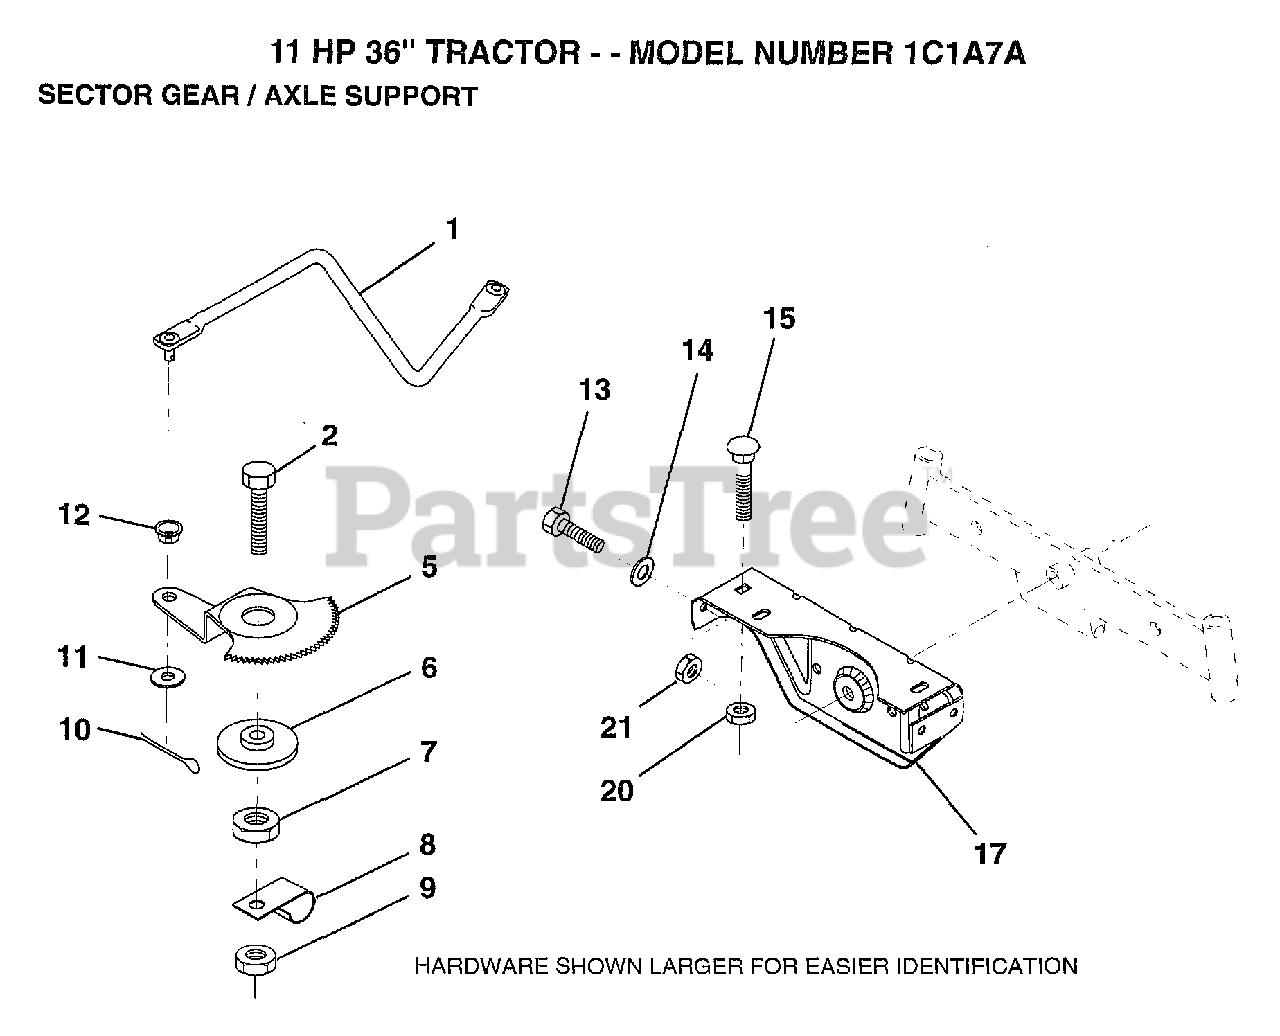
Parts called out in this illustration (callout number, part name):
1	DRAG LINK
2	"BOLT,HEX"
5	GEAR SECTOR
6	BUSHING
7	NUT
8	CLIP INSULATOR
9	NUT LTV
10	COTTER PIN
11	WASHER
12	BUSHING.DRAGLINK
13	BOLT
14	WASHER
15	BOLT
17	SUPT AXLE FRONT
20	NUT
21	NUT
